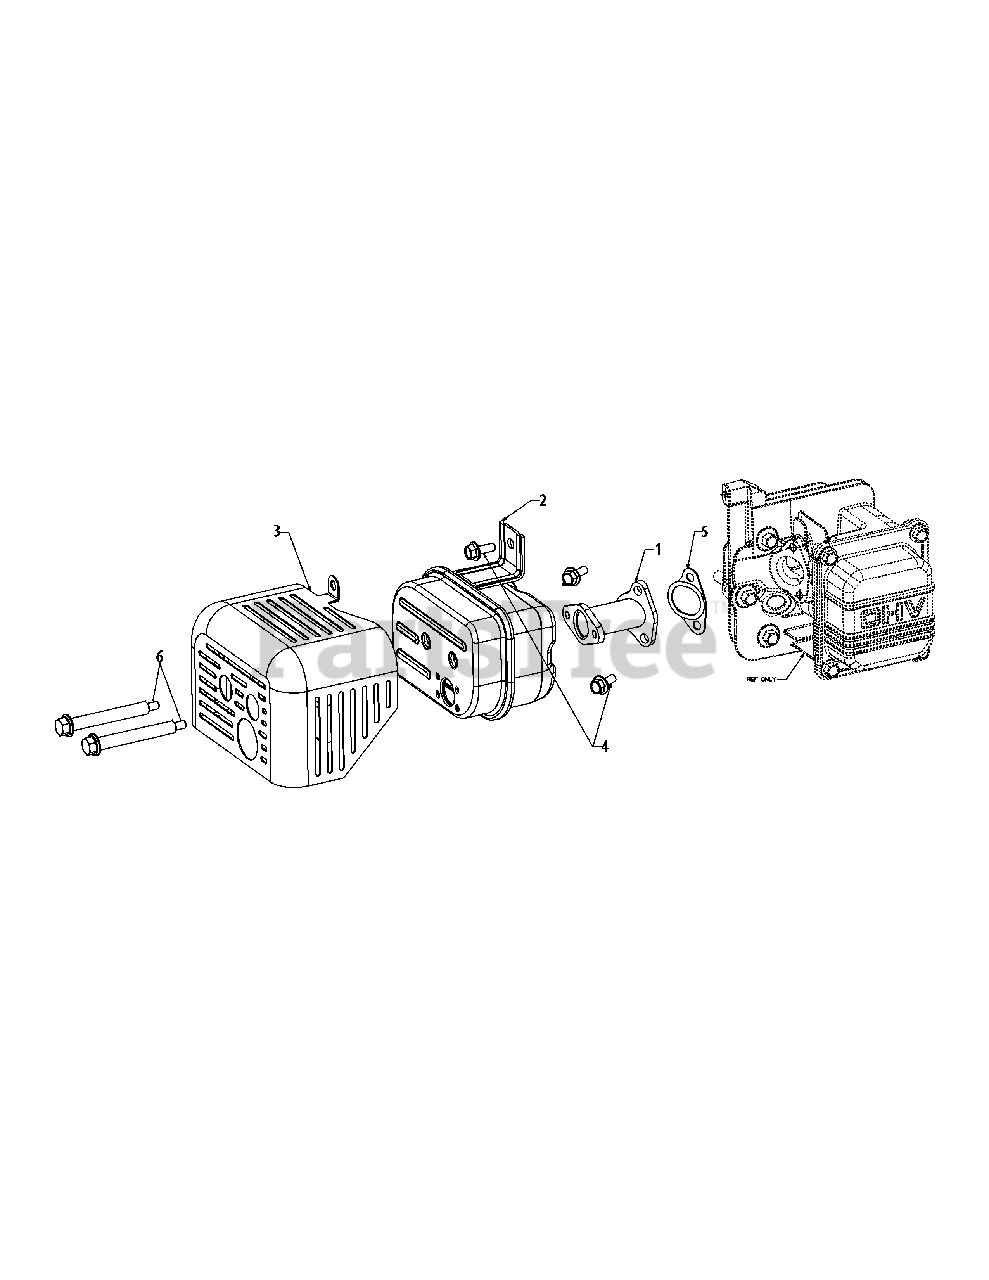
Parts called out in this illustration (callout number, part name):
1	Tube Asm-Exh 195
2	Muffler Asm-Clmsh
3	Cover-Muffler Asm
4	Hhflg-M6-1:16 Cl8.
5	Gasket-Exhaust
6	Screw-Shoulder 9.5
